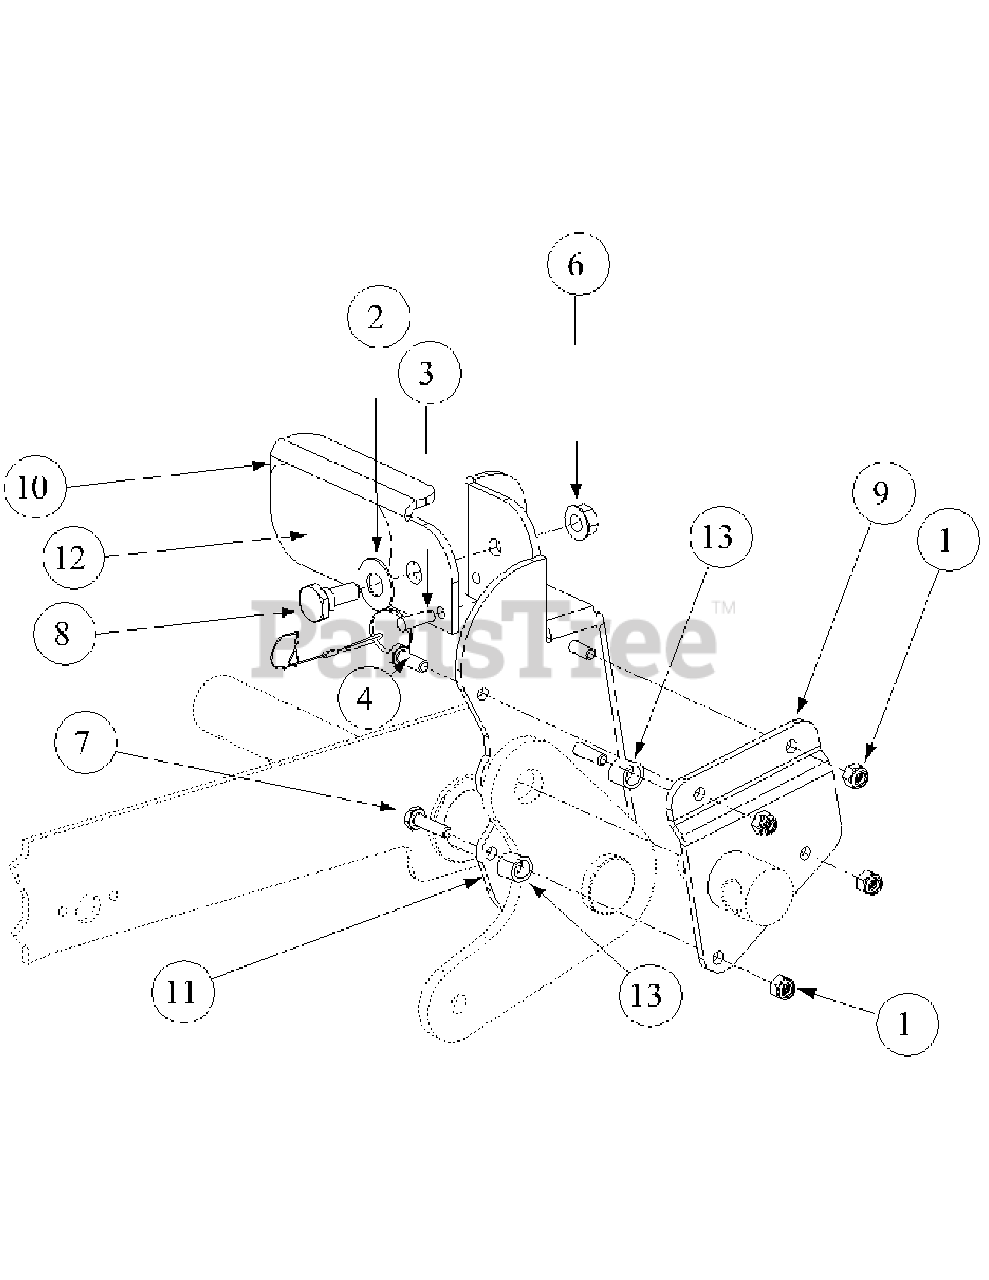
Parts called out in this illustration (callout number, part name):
1	Lock Nut, Nylon Insert, 1/4-20
2	Washer, 1/2 x 1 Shim
3	Detent Pin w/Lanyard, 1/4"
4	Hex Cap Screw, 1/4-20, .75
6	Hex Nut, Flange Lock 3/8-16
7	Hex Cap Screw, 1/4-20, 1.00
8	Shoulder Screw, .50x.27 Lg., 3/8-16
9	Foot Lift Backup Pedal
10	Deck Foot Pedal Lift
11	Deck Foot Pedal Lift Holder
12	Deck Foot Lift Pad
13	Turnbuckle Sleeve
